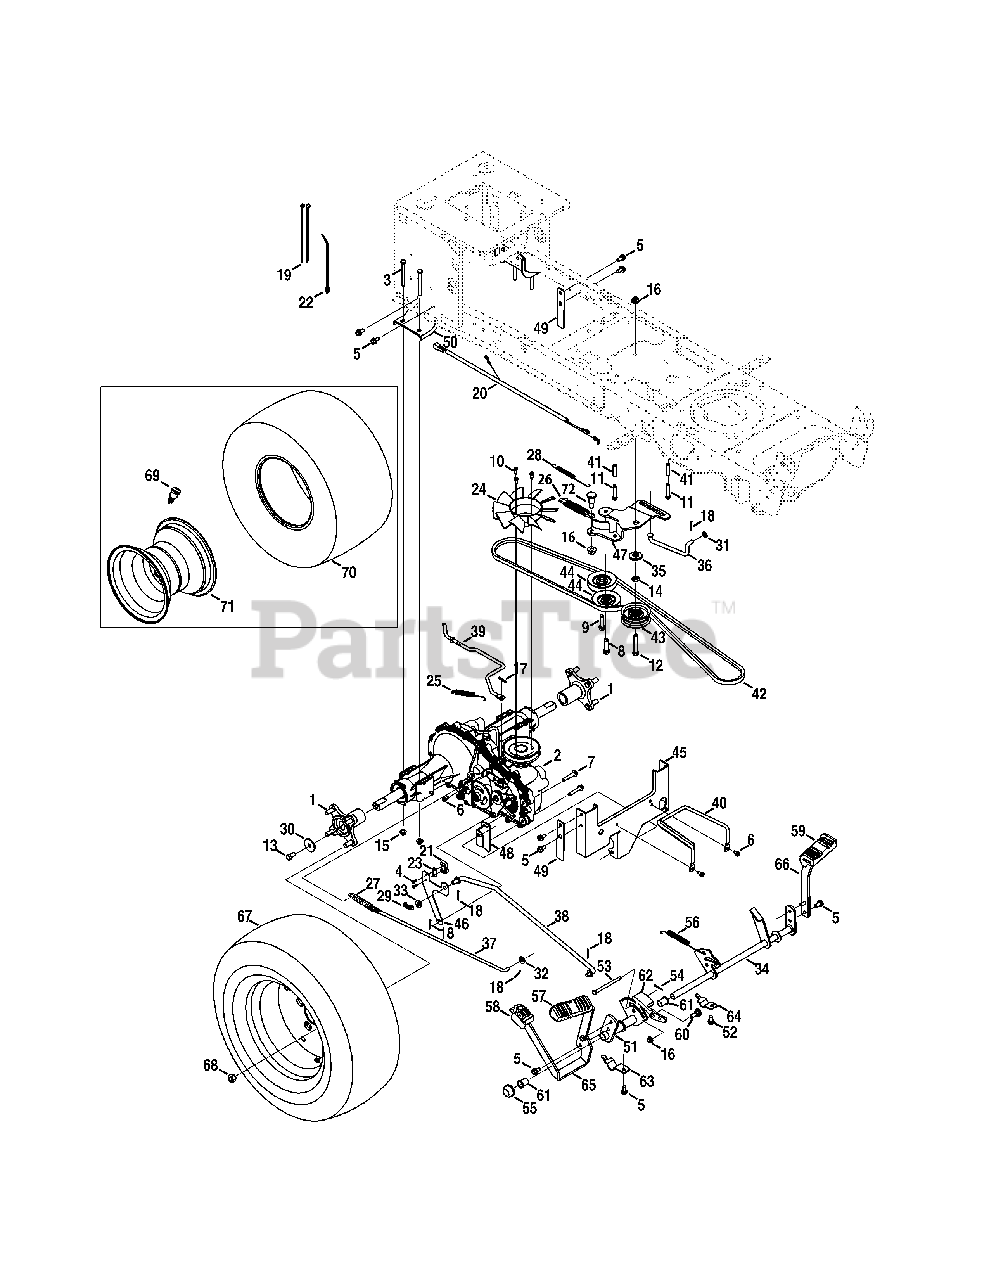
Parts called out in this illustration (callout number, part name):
1	Wheel Assembly Hub
2	Transmission
3	Hex Screw, 5/16-18:3.00
4	Screw, #8-18:0.500
5	Taptite Screw, 5/16-18:.750
6	Taptite Screw, 1/4-20:0.500
7	Taptite Screw, 5/16-18:1.750
8	Taptite Sems Screw, 3/8-16:1.500
9	Taptite Sems Screw, 3/8-16:1.875
10	Screw, #12-24:0.625
11	Taptite Screw, 1/4-20:1.625
12	Hex Screw, 3/8-16:2.25
13	Hex Screw, 3/8-16:.750
14	Jam Nut, 7/16-20
15	Flangelock Nut, 5/16-18
16	Flangelock Nut, 3/8-16
17	Cotter Pin, .072 DIA. x 1.13 LG
18	Cotter Pin, 3/32:1.0
19	Cable Tie, 3/16 x .05 x 7.4
20	Jumper Harness
21	Short Spring Switch
22	Push Mount Cable Tie 7.5 LG
23	Insulator Nut Plate
24	Blade Fan
25	Extension Spring, .50 DIA x 5.0 LG
26	Extension Spring, 1.00 DIA x 4.75
27	Extension Spring, .59 OD x 4.00 LG
28	Extension Spring, .38 DIA x 5.6
29	Extension Spring, .375 OD x 1.44 LG
30	Flat Washer, .390 x 1.500 x .134
31	Flat Washer, .330 x .630 x .0635
32	Flat Washer, .344 x .750 x .120
33	Flat Washer, .407 x .812 x .135
34	Brake Control Assembly
35	Shoulder Spacer, 1.375 x .380 x .183
36	Footpedal Bypass Transmission Rod
37	Brake Rod
38	Control Rod
39	Disengage Rod
40	Belt Keeper, 5/16
41	Spacer, 260 x .372 x 1.420 LG
42	V Belt, 4L x 77.0
43	Flat Idler Pulley, 2.75 OD
44	V Idler Pulley, 3.06
45	Torque Bracket
46	Switch Bracket
47	Center Idler Bracket
48	Deck Bracket
49	Plate Bracket
50	Axle Bracket
51	Pedal Bracket Assembly
52	Taptite Screw, 5/16-18:0.625
53	Clevis Pin, 5/16 x 3.985
54	Bow-Tie Cotter Pin
55	Push Cap
56	Extension Spring, .63 DIA x 4.95 LG
57	Forward Pedal Pad
58	Reverse Pedal Pad
59	Brake Pedal Pad
60	Shoulder Bolt, .500 x .270:3/8-16
61	Flange Bearing, .630 ID x .695 OD x .60
62	Cruise Latch
63	Pedal Support Bracket
64	Pedal Support Bracket, 5/8
65	Drive Pedal Bracket
66	Brake Pedal Bracket
67	Complete Wheel
68	Lug Nut, 7/16-14
69	Air Valve
71	Rim Assembly
